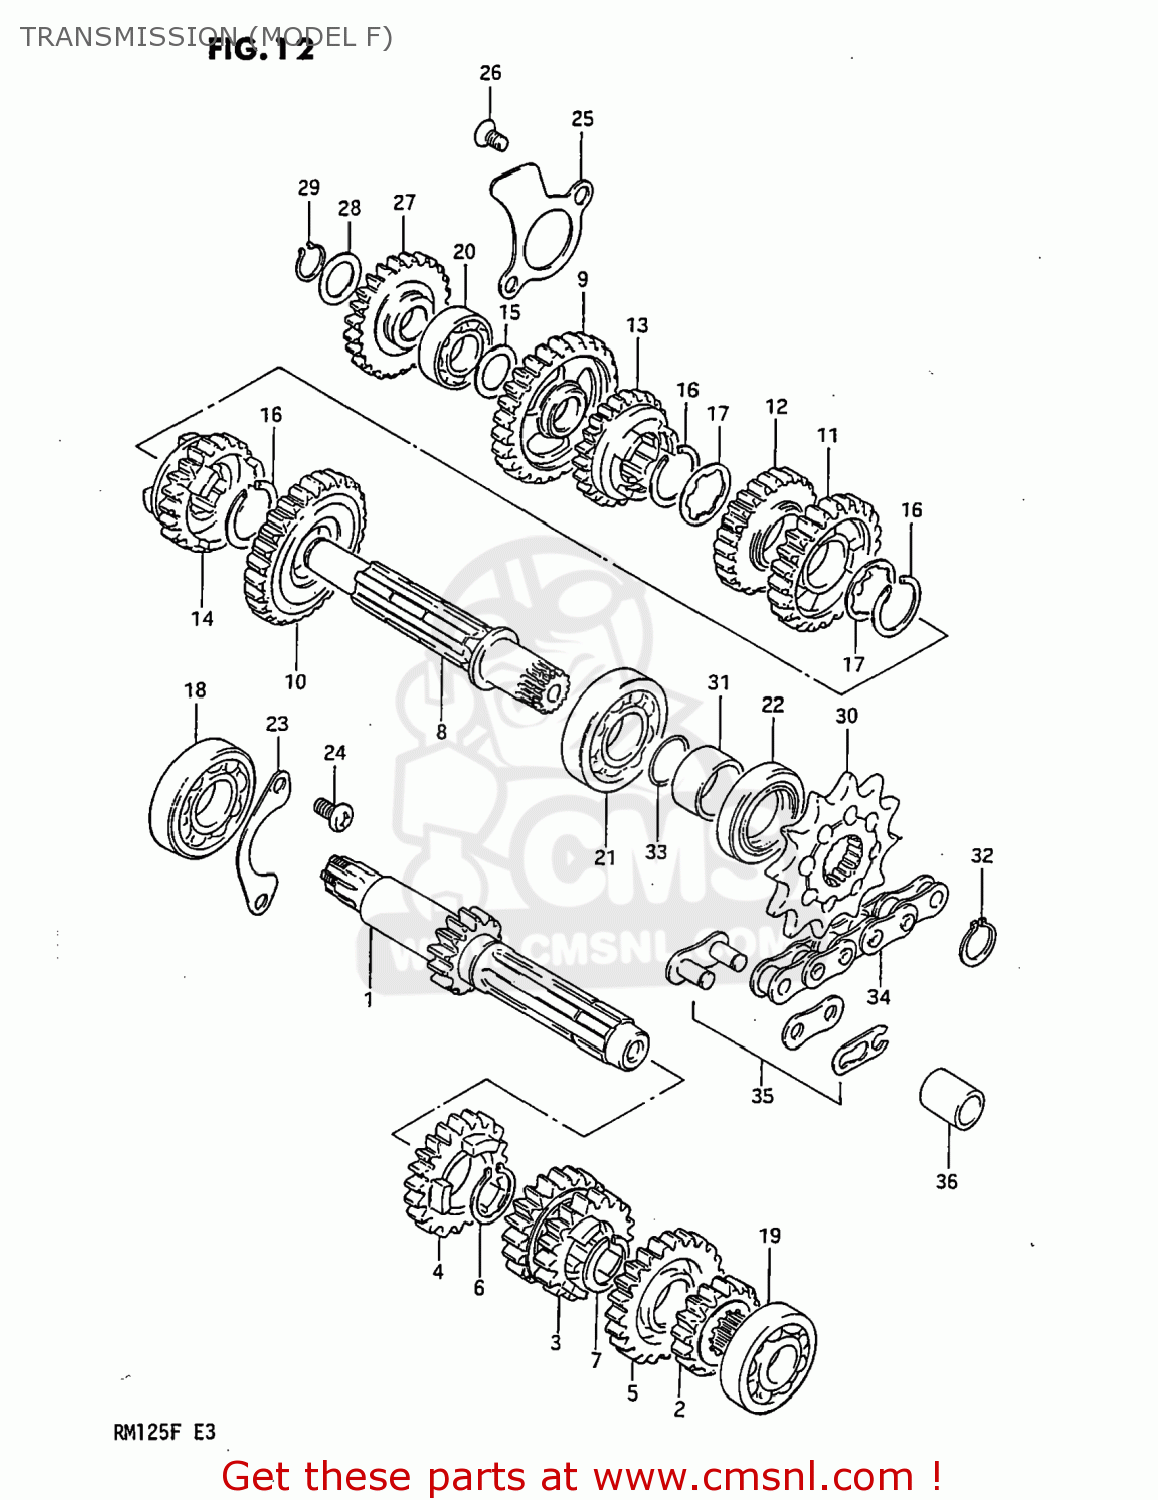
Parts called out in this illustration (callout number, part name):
1	SHAFT,COUNTER
2	GEAR,SECOND DRIVE
3	GEAR,THIRD/FOURTH DRIVE
4	GEAR,FIFTH DRIVE
5	GEAR,SIXTH DRIVE
6	CIRCLIP
7	CIRCLIP
8	SHAFT,DRIVE
9	GEAR,FIRST DRIVEN
10	GEAR,SECOND DRIVEN
11	GEAR,THIRD DRIVEN
12	GEAR,FOURTH DRIVEN
13	GEAR,FIFTH DRIVEN
14	GEAR,SIXTH DRIVEN
15	WASHER,THRUST
16	CIRCLIP
17	WASHER,LOCK
18	BEARING
19	BEARING
20	BEARING
21	BEARING(20X47X14)
22	SEAL,OIL(25X40X7)
23	RETAINER,CNTR SHAFT BEARING
24	SCREW 6X12
25	RETAINER,DRIVESHAFT
26	SCREW
27	GEAR,KICK STARTER IDLE
28	WASHER,THRUST
29	CIRCLIP,15MM
30	SPROCKET,ENGINE
31	SPACER(20X25X12.5)
32	CIRCLIP
33	O RING(D:1,ID:19.5)
34	CHAIN ASSEMBLY,DRIVE
35	JOINT ASSEMBLY,CHAIN
36	CUSHION 12X20X20
